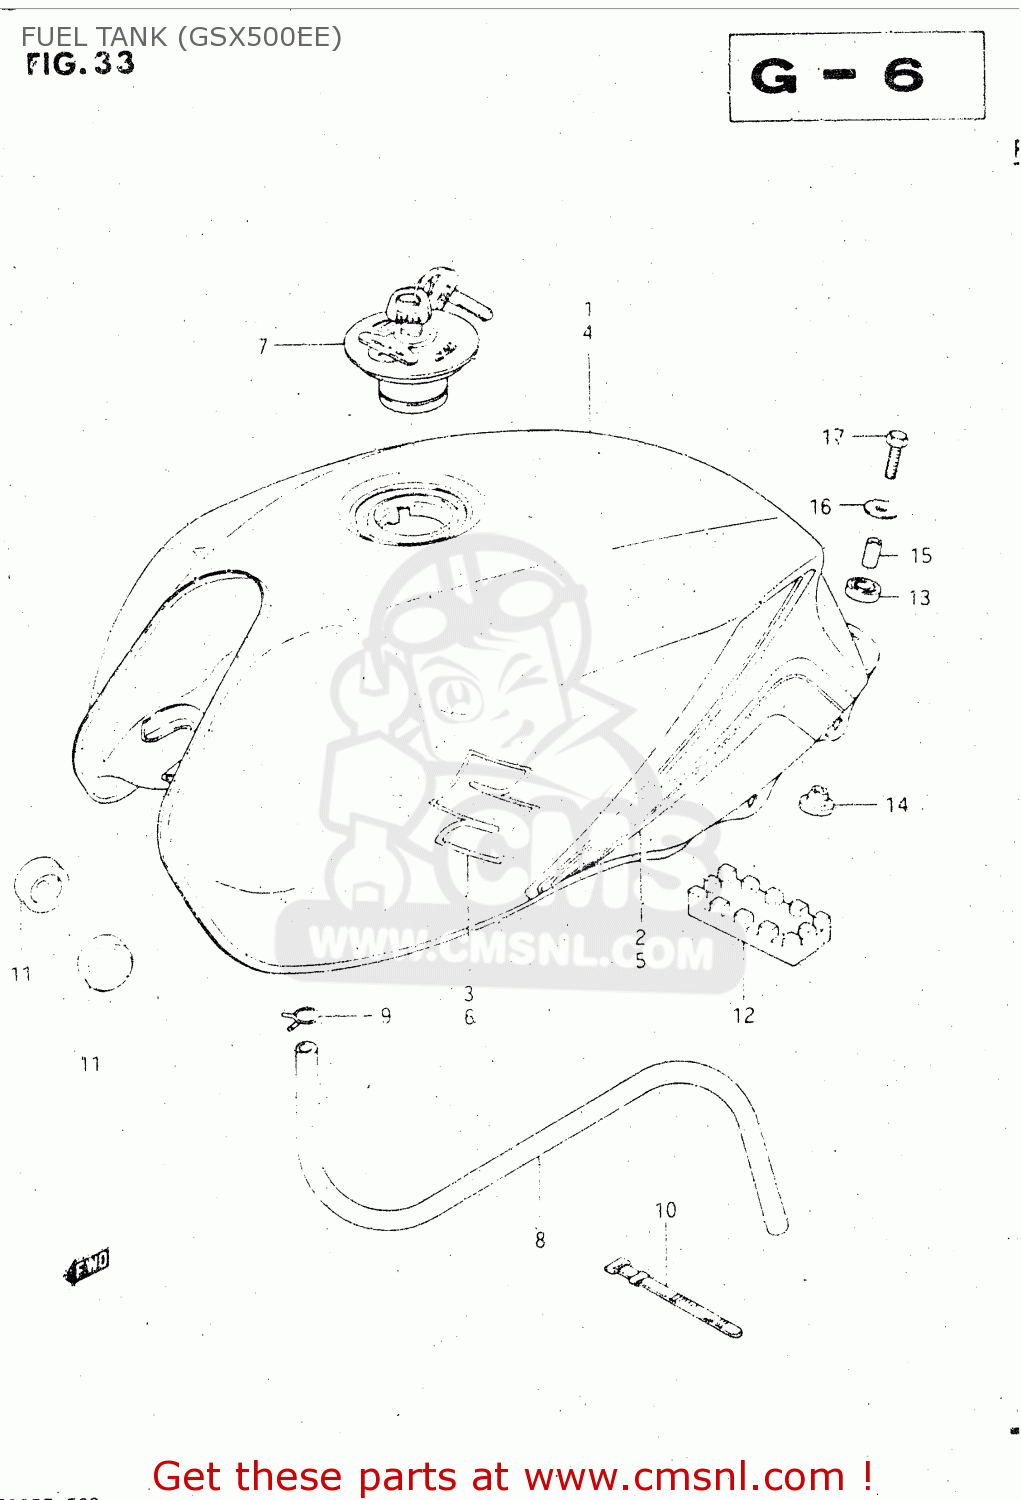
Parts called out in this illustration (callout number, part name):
1	TANK ASSY, FUEL (BLACK)
2	TAPE SET, FUEL TANK
3	EMBLEM
4	TANK ASSY, FUEL (RED)
5	TAPE SET, FUEL TANK
6	EMBLEM
7	CAP ASSY,FUEL TANK
8	HOSE,FUEL
9	CLIP
10	CLAMP(L:187)
11	CUSHION
12	CUSHION,FUEL TANK
13	CUSHION
14	CUSHION
15	SPACER (6.4X9X20)
16	WASHER (6.5X24X1.6)
17	BOLT
